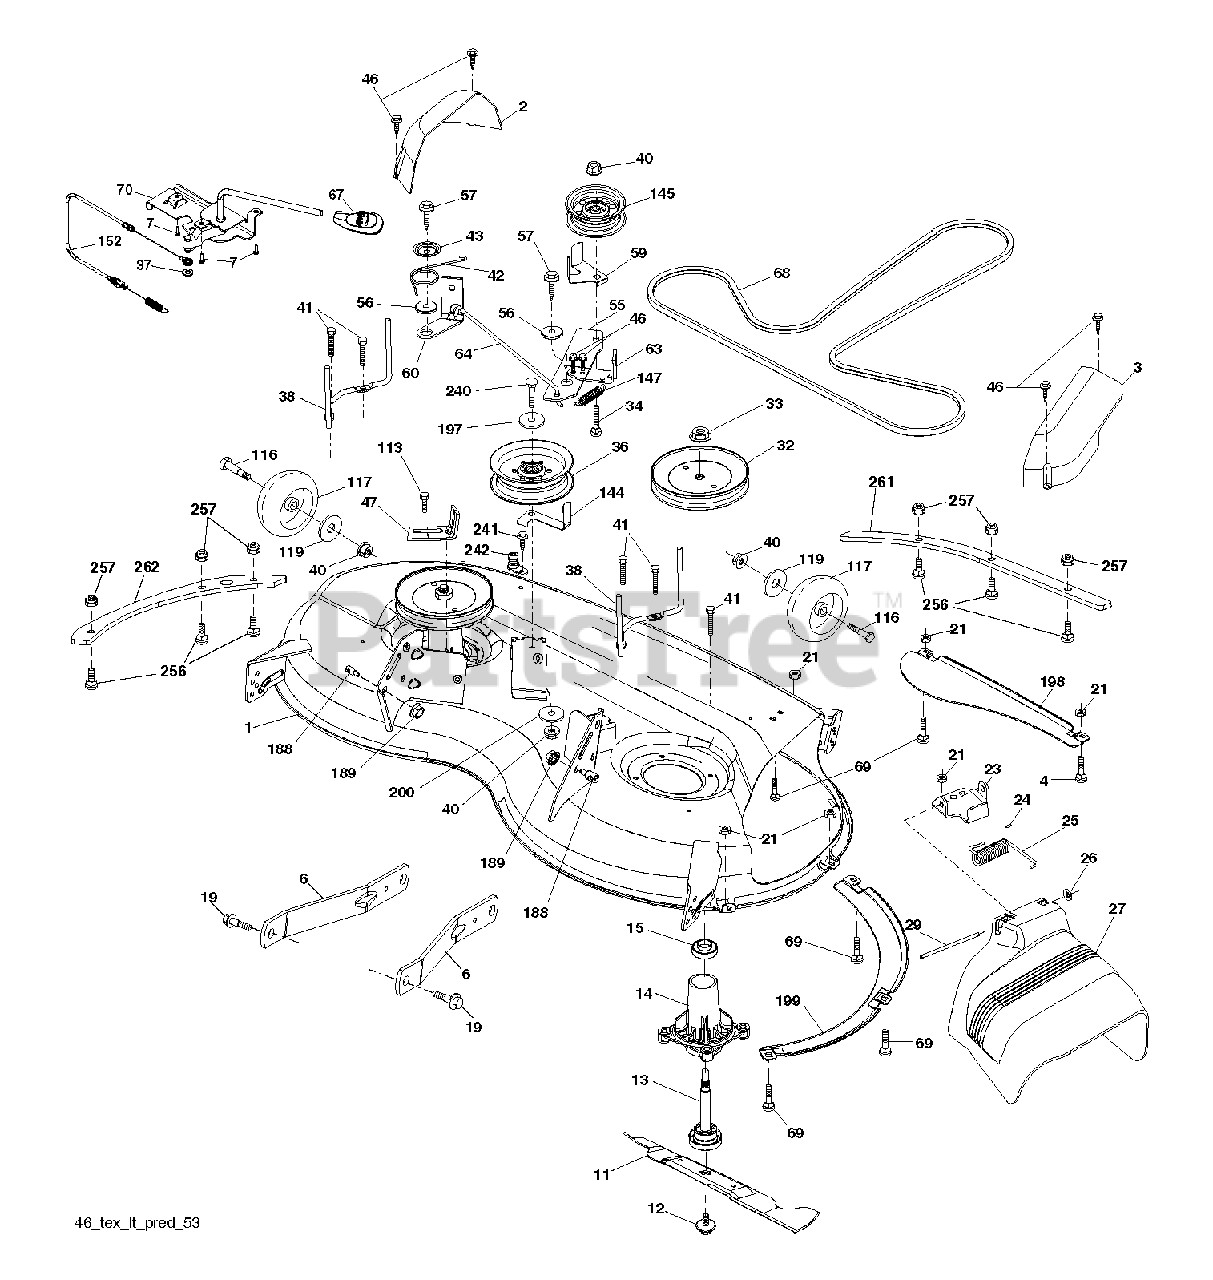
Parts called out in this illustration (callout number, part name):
1	DECK SVC 46"
2	COVER.MANDREL.RH.46"
3	COVER.MANDREL.LH.46"
4	BOLT
6	ARM.SUSPENSION.MOWER.R
7	SCREW.#10 X 0.750.BOS
11	BLADE.MOWER.46".HI.LIFT
12	SCREW.SEMS.7/16-20X1.HEX.HEAD
13	SHAFT ASM.MNDRL.N/GREASEABLE
14	HOUSING.MANDREL.4PT.
15	BEARING.MANDREL.TOP.EXTENDED
19	BOLT.SHOULDER
21	LOCKNUT
23	BRKT.DEFLECTOR.38"2005+
24	CAP-SLEEVE LT
25	SPRING.TORSION.DEFLECT
26	NUT PUSH M
27	SHIELD.DEFLECTOR.MOWER.46"BLAC
29	ROD.HINGE
32	PULLEY.MANDREL.5.438.PD
33	NUT.FLANGE.LOCK.TOP
34	BOLT.3/8-16X1.50
36	PULLEY.IDLER.2006
37	WASHER
38	KEEPER.BELT.MANDREL.PULLEY
40	NUT LOCK FLG 3/8-16 UNC
41	BOLT.HEX.WASHR.HED.313-18X1.19
42	SPRING.TORSION.BRAKE
43	SRPING.TORSION.RETAINE
46	SCREW.1/4-20X5/8
47	BRKT.CLUTCH.CABLE
56	SPACER.RETAINER
57	SCREW 3/8-16X1
59	GUARD, BELT
60	ARM BRAKE MOWER RH 38"
63	ARM BRAKE MOWER
64	LINKAGE BRAKE
67	HANDLE.CLUTCH.CABLE.LT
68	V-BELT
69	BOLT
70	CLUTCH.ASM.MANUAL.YT.PREDATORQ
113	BOLT.5/16HEX.WHS.HD
116	BOLT.SHOULDER.3/8-16X3-5/8.
117	WHEEL. GUAGE RALLY
119	WASHER
144	KEEPER.BELT.MOWER
145	PULLEY.IDLER.48"PRIMARY
147	SPRING RETURN
152	CABLE.MECHANICAL.CLUTCH
188	STUD.FASTNER.W/ANTI-ROTATE
189	NUT LOCK HEX FLANGE 5/16-18
197	WASHER
198	BAFFLE CENTER FRONT
199	BAFFLE FRONT RH
200	WASHER.13/32 X 1 X 1/2.11GUARD
240	BOLT-HEX EAK
241	SCREW.TT.#10-32X.5.3/8.FLANGE
242	PORT.WASHOUT
256	SCREW.BUTTONHEAD.1/4-20X1
257	NUT T
261	PLATE.REINFORCE.46.BOLT.ONX431
262	PLATE.REINFOR.46.SIDEBOLT.X431
